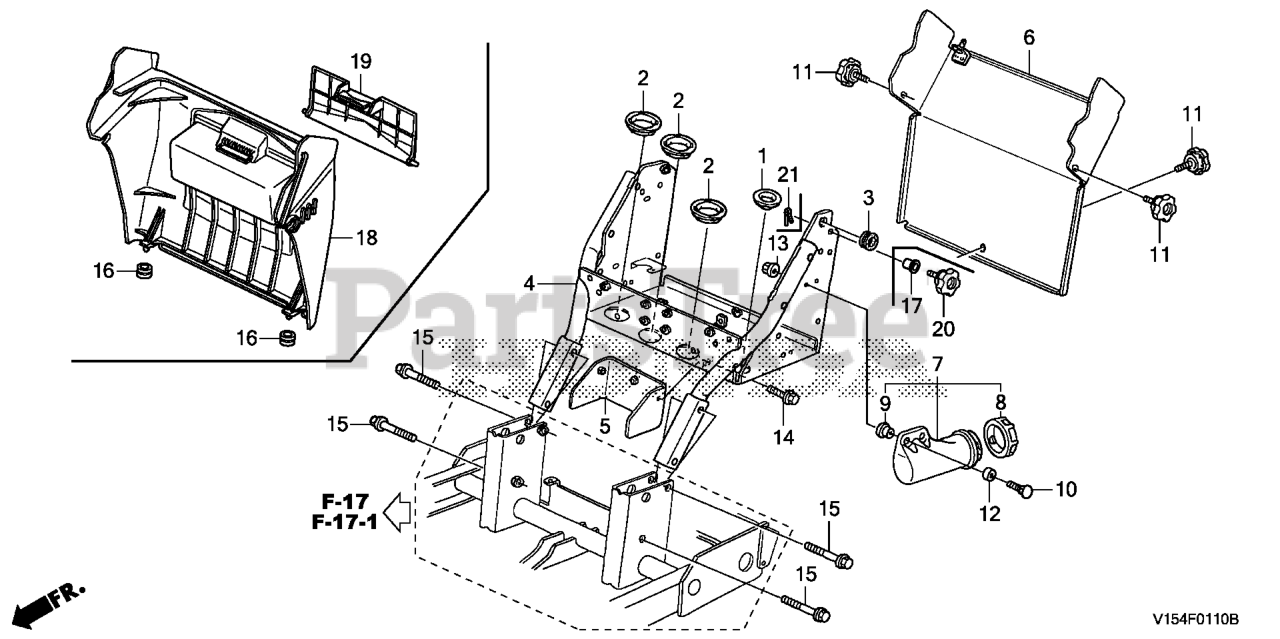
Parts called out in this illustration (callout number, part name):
1	PROTECTOR A, WIRE
2	PROTECTOR B, WIRE
4	PIPE, HANDLE (LOWER)
5	PROTECTOR, MOTOR JOINT HARNESS
14	BOLT, FLANGE (6X10)
15	BOLT, FLANGE (8X55)
16	GROMMET, RESERVE TANK
17	COLLAR, SLIDER (NOT AVAILABLE)
18	COVER, RR.
19	COVER, TOOL
20	BOLT, KNOB
21	PIN, SPLIT (2.5X18)
